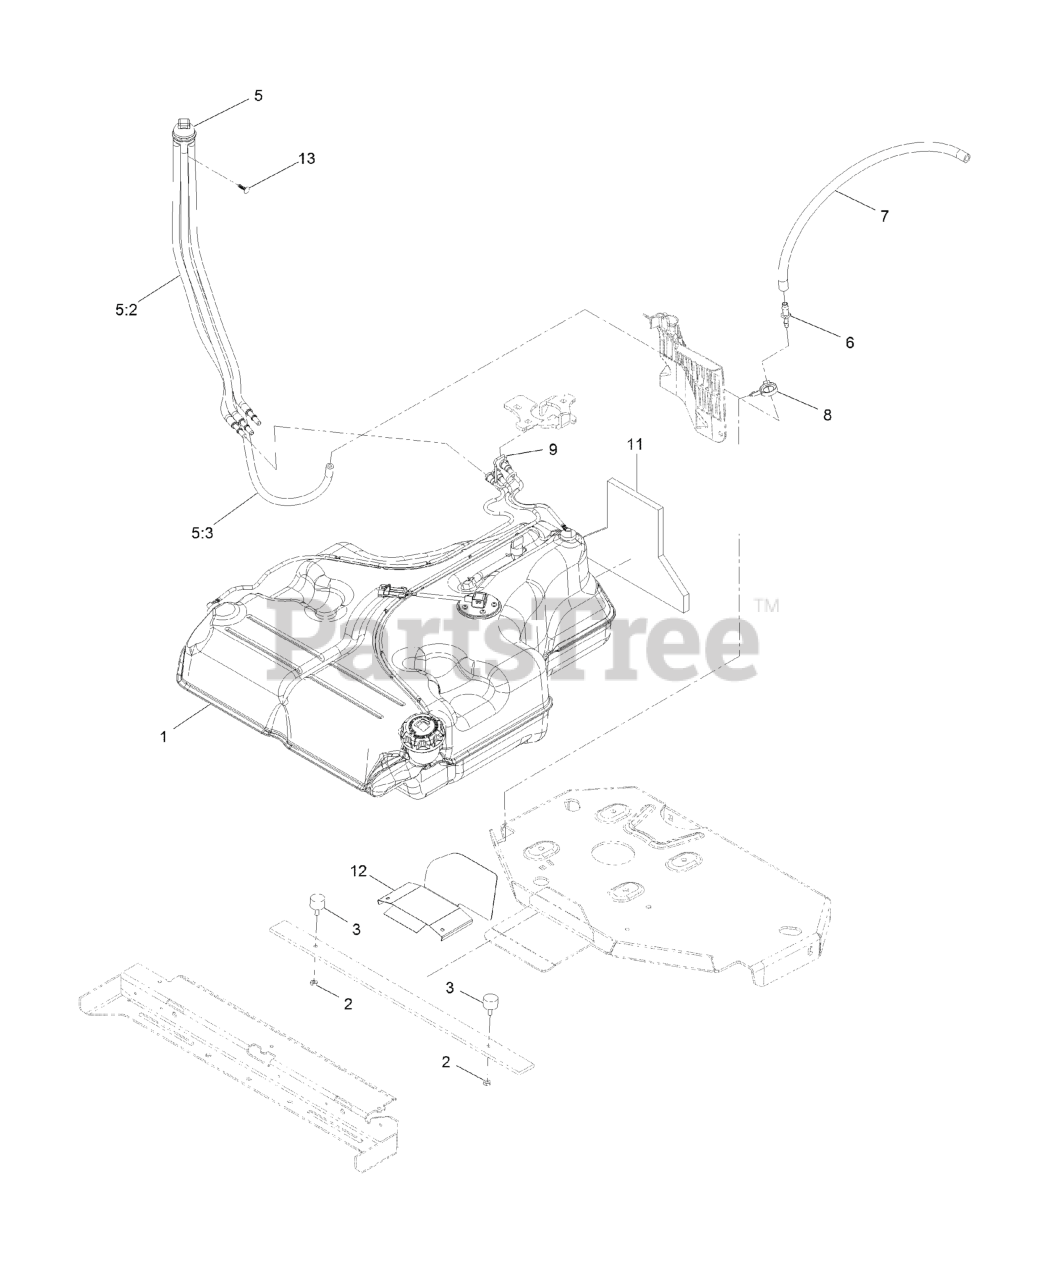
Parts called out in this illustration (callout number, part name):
1	FUEL TANK ASM
2	NUT-JAM
5	FUEL MANIFOLD VENT ASM
5:2	HOSE-FUEL
5:3	HOSE-FUEL
6	FITTING-STRAIGHT
7	HOSE-FUEL
8	CLAMP-HOSE
9	RETAINER-LINE, VAPOR
11	INSULATION-FOAM, FUEL TANK
12	GUARD-EXHAUST
13	PLUG-PLASTIC
